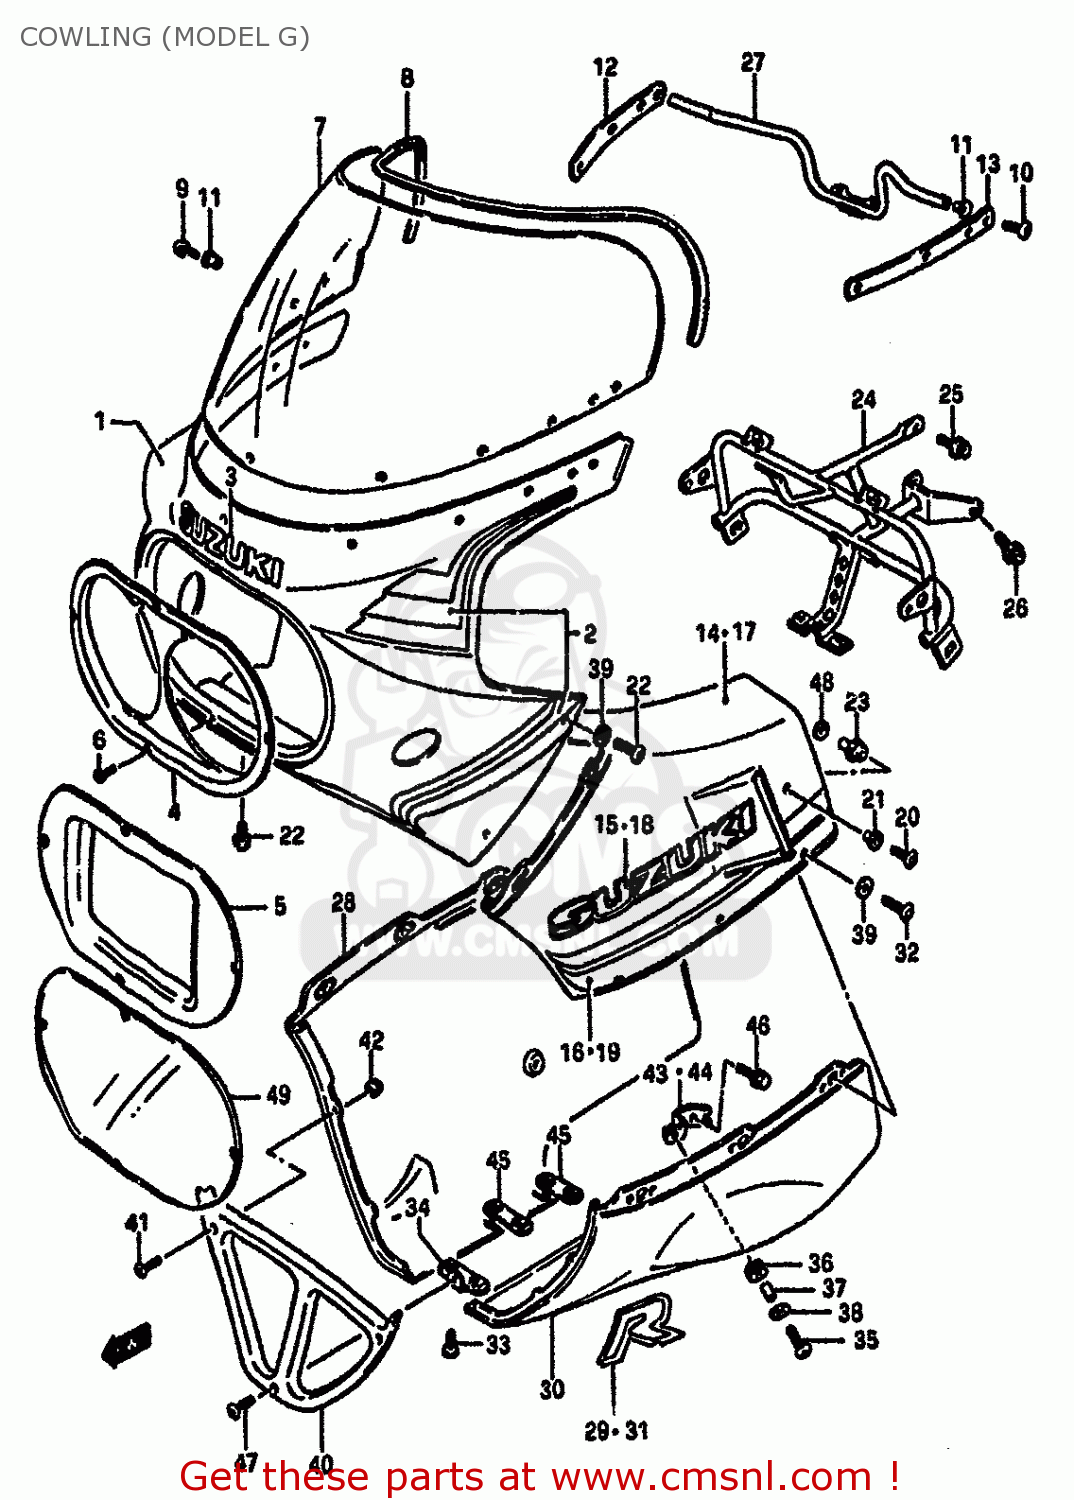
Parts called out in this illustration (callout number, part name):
1	COWLING SET
2	TAPE SET,COWLING
3	EMBLEM,LEG SHIELD
4	COVER,COWLING FR
5	COVER,FRONT (RED)
6	SCREW
7	WINDSCREEN
8	MOLDING
9	SCREW(5X14)
10	SCREW(5X18)
11	NUT,COWLING SCREEN
12	PLATE,RR VIEW MIRROR,R
13	PLATE,RR VIEW MIRROR,L
14	COVER ASSEMBLY,COWLING
15	EMBLEM
16	TAPE SET,COWL SIDE RH
17	COVER,COWLING SIDE,LEFT
18	EMBLEM
19	TAPE SET,COWL SIDE LH
20	SCREW(6X12)
21	WASHER
22	SCREW(6X16)
23	CUSHION,COWLING
24	BRACE,COWLING
25	BOLT
26	BOLT
27	BRACE,COWLING BODY RR
28	COVER,COWLING,LOWER,RIGHT
29	EMBLEM
30	COVER,COWLING,LOWER,LEFT
31	EMBLEM
32	SCREW(6X16)
33	SCREW(6X16)
34	BRACE,COWLING LWR COVER
35	SCREW(6X20)
36	CUSHION
37	SPACER
38	WASHER(6.5X18X1)
39	WASHER
40	COVER,COWLING,LOWER,FRONT
41	SCREW(5X14)
42	NUT
43	BRACE,COWLING LWR,R
44	BRACE,COWLING LWR,L
45	BRACE,COWLING LWR COVER RR
46	BOLT
47	SCREW(6X16)
48	WASHER
49	COVER,HEADLAMP
